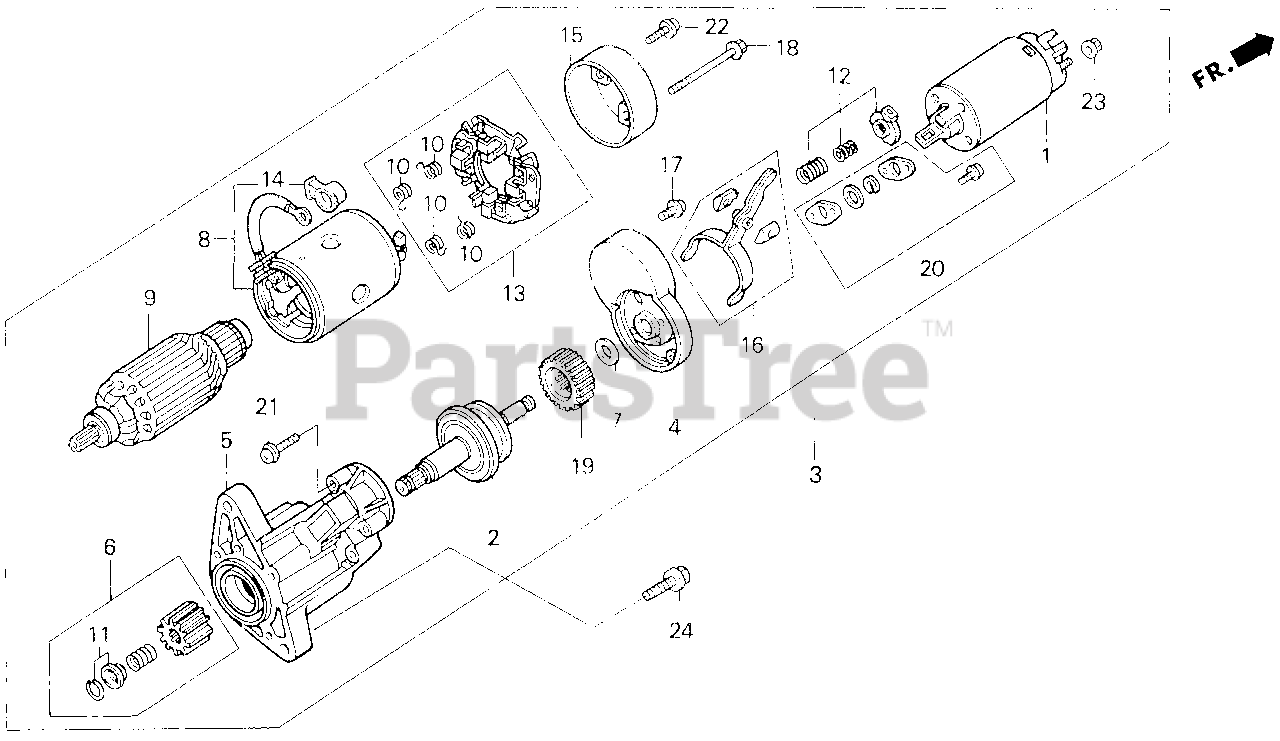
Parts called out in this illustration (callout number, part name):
1	SWITCH ASSY., MAGNETIC
2	CLUTCH, OVERRUNNING
3	MOTOR ASSY., STARTER
4	BRACKET, CENTER
5	BRACKET, FR.
6	GEAR SET, PINION
7	WASHER, THRUST
10	SPRING, BRUSH
11	STOPPER SET
12	SPRING SET
13	HOLDER, BRUSH
14	COVER, TERMINAL
15	BRACKET, RR.
17	BOLT A, THROUGH
18	BOLT B, THROUGH
19	GEAR, IDLE
20	COVER SET, SHAFT
21	SCREW, FLANGE (6X23)
22	SCREW, FLANGE (5X8.5)
23	NUT-WASHER (8MM)
24	BOLT, FLANGE (10X35)
